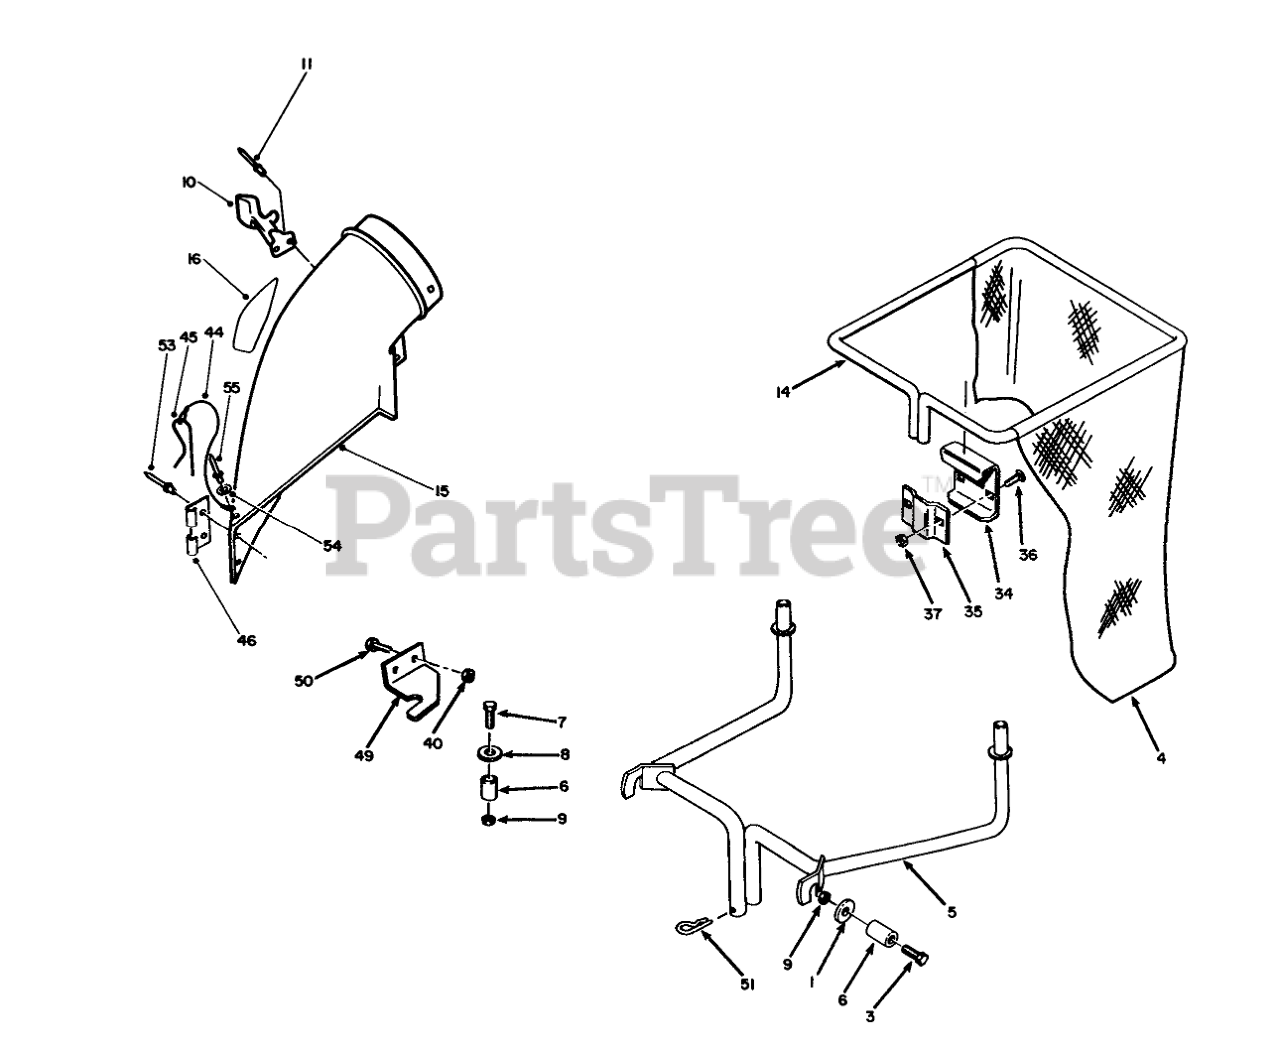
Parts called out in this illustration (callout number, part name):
1	WASHER
2	RIVET-BLIND
3	Bolt
4	Bag
5	Bracket-Quick Attach
6	SPACER
7	BOLT
8	Washer
9	NUT
10	Latch-38"
11	NUT-LOCK, NI
14	Bag Frame
15	Chute Assembly (Incl. Ref. #10-11, 16, 44-46 & 53-55)
16	DECAL-DANGER
21	Washer
34	Bag Hanger
35	Clamp
36	Bolt
37	Nut
40	Nut
44	LANYARD
45	PIN-LOCKING, CHUTE
46	BRACKET-MOUNTING, CHUTE
49	LATCH-BAGGER ELBOW
50	Bolt
51	Hairpin
53	RIVET-BLIND
54	NUT-LOCK, NI
55	RIVET-BLIND
